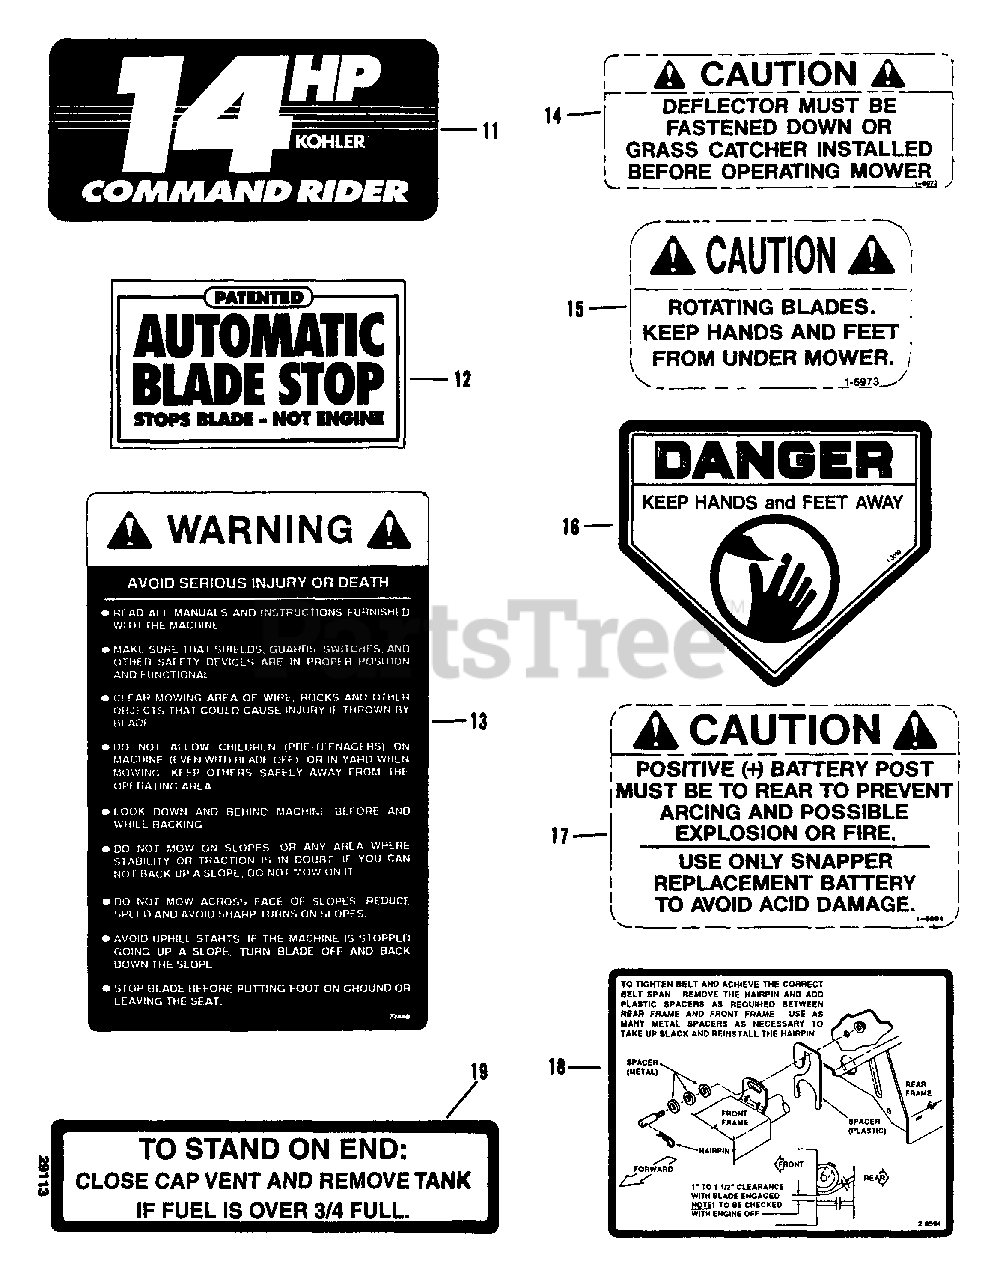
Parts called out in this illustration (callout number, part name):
11	DECAL, 14 HP
12	DECAL, Auto Blade Stop (Point of Purchase Decal)
13	DECAL, Safety Instruction Warning
14	DECAL, Caution Deflector
15	DECAL, Caution Rotating Blades
16	DECAL, Danger
17	DECAL, Caution Battery
18	DECAL, Belt Adjustment
19	DECAL, Caution Fuel
